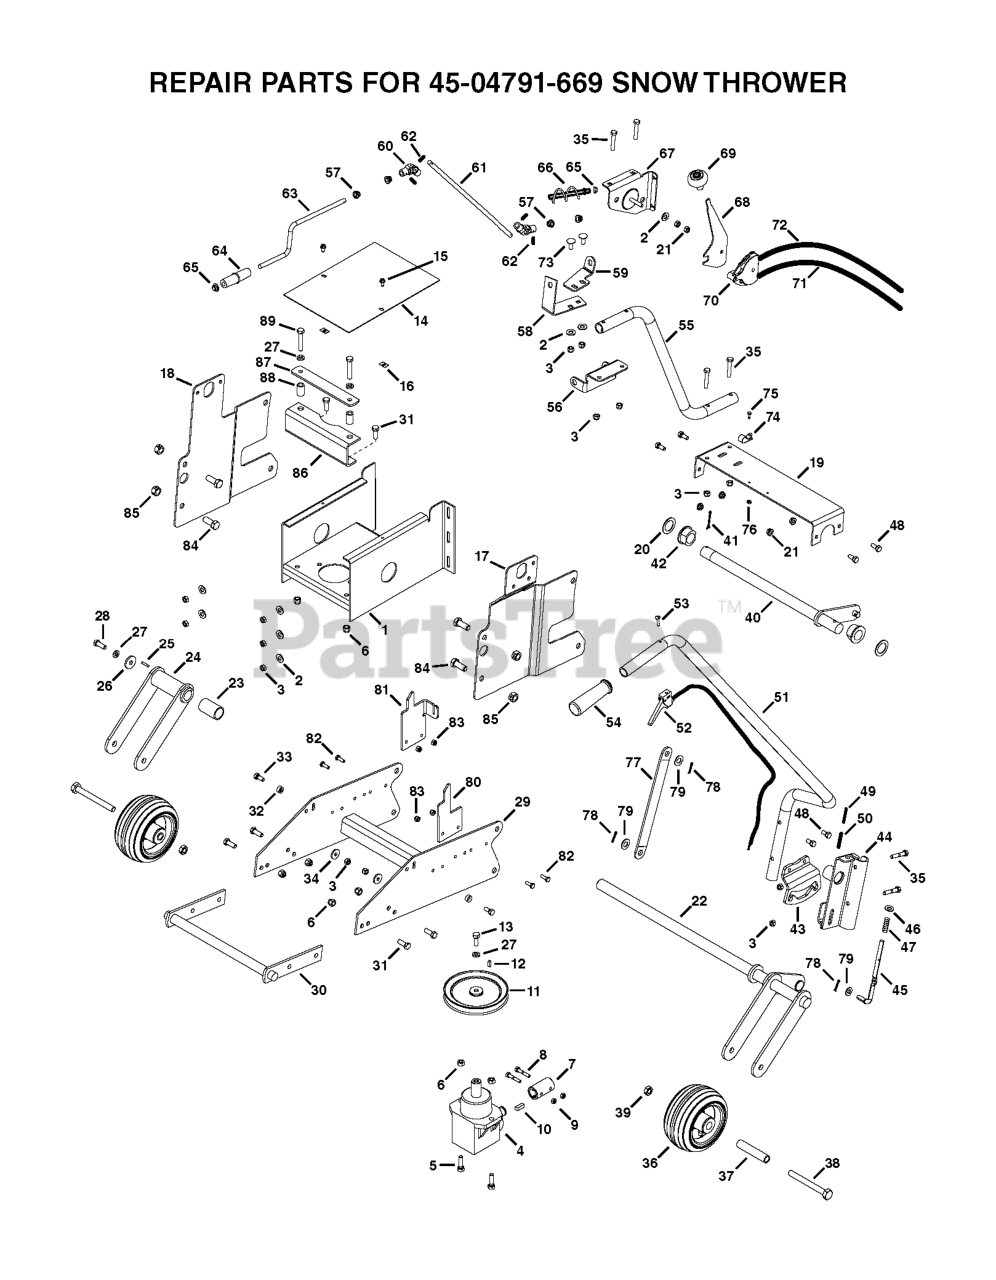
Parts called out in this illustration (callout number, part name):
1	MOUNTING BRAKET
5	HEX BOLT
12	WOODRUFF KEY
17	MOUNTING BRACKET
18	MOUNTING BRACKET
27	LOCK WASHER
31	HEX BOLT
39	NUT LOCKING
41	COTTER PIN
48	HEX BOLT 5/16ÄX3/4Ä
62	PIN RETAINING SCREW
66	CRANK ASSEMBLY
70	CABLE GUIDE
